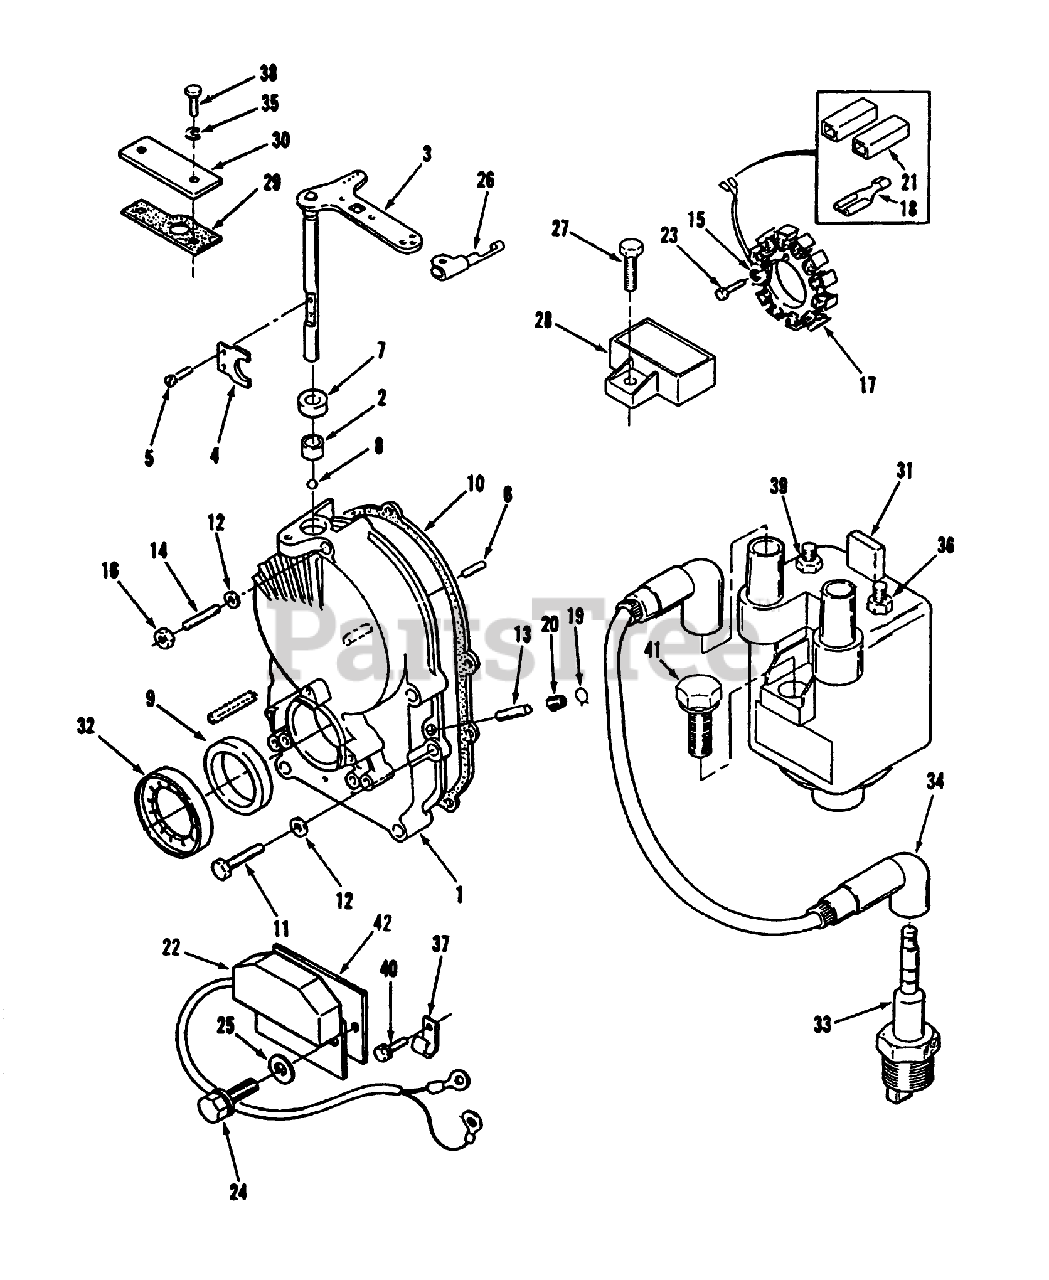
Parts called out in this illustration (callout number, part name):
1	Kit-Gearcase (Incl. Ref. #2-9, 13, 19, & 20)
2	BEARING
3	SHAFT AND ARM
5	SCREW-PAN HD
6	Washer
8	Bearing
10	Gasket
11	Bolt
12	WASHER
13	TUBE-PORT, VACUUM
14	Stud
15	WASHER-LOCK
16	Nut
17	Stator w/Terminals
18	Stator Leads Terminal
19	CLAMP
20	CAP-FUEL OUTLET
21	BODY-TERM. CONNECTOR KIT
22	Control-Ignition
23	Screw-HH
24	Bolt
25	WASHER-LOCK
27	Bolt
28	Regulator
29	Gasket-Plate
30	Plate
31	Coil-Ignition
32	Rotor
33	SPARK PLUG
34	WASHER-FLAT
35	WASHER-FLAT
36	Nut
37	Clip
38	SCREW - CAP HEX HEAD
39	Nut
40	Bolt
41	Bolt
42	Insulator
